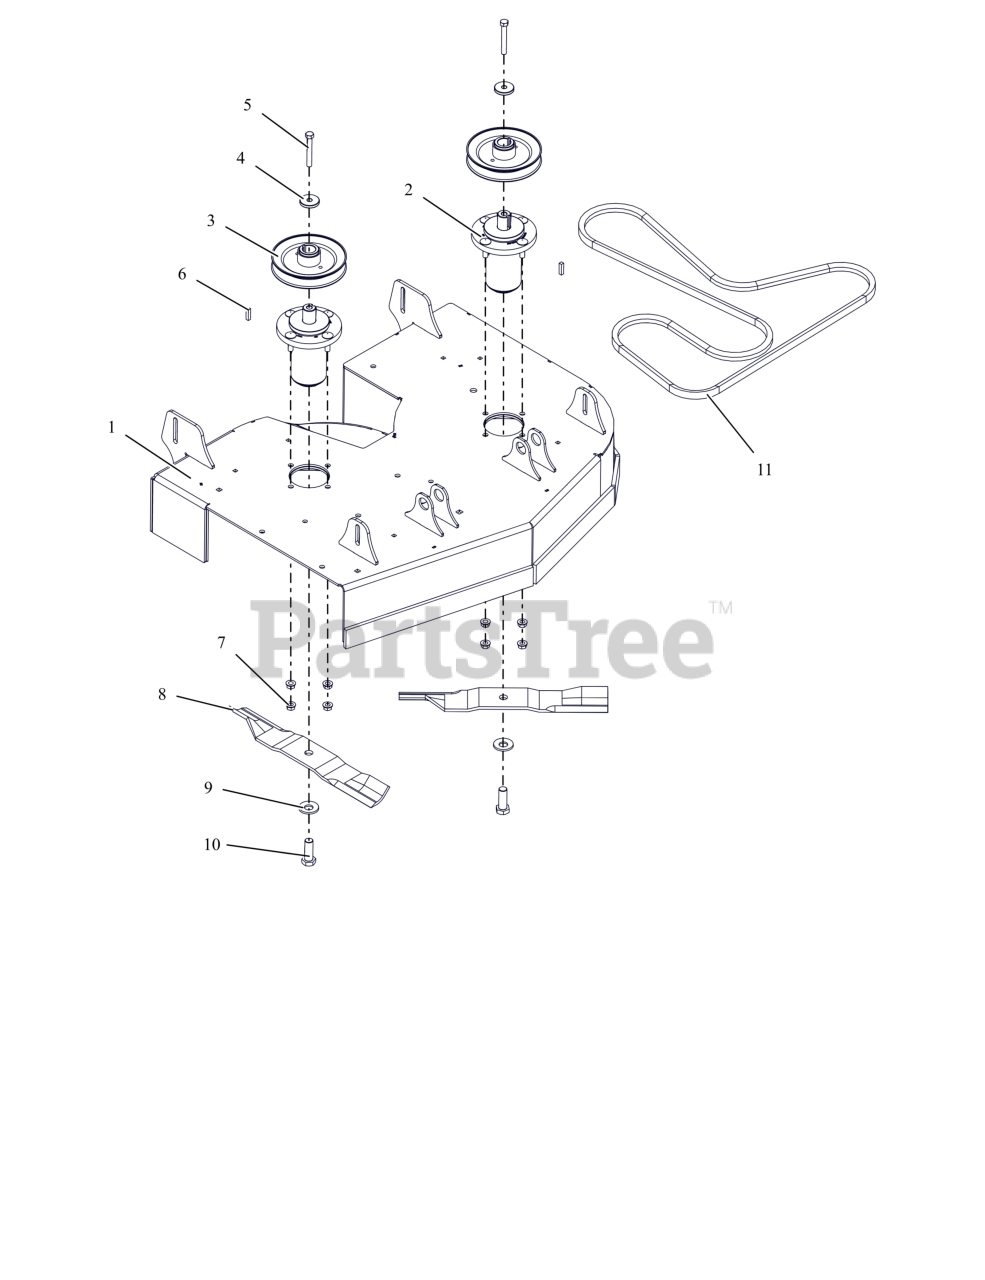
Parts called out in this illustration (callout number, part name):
1	32" DECL WLDMT W/SAFETY DECALS
2	ASM, MAINT FREE ALUM SPINDLE
3	PULLEY, V-1" ID X 5.75" OD
4	RETAINER, SHEAVE
5	BLT, HEX .38-16X2.75 G8 ZCC
6	KEY, SQ .25X.25X1.00 RC 40-50
7	NUT-LK-CTR-FLG .375-16 GF ZCC
8	BLADE, 16.19" MOWER (HI-LIFT)
9	WSHR-BLVL .669X1.535X.138
10	BLT, HEX .62-18X1.75 G8 ZCC
11	BELT- B-SECTION EPDM RAW EDGE
